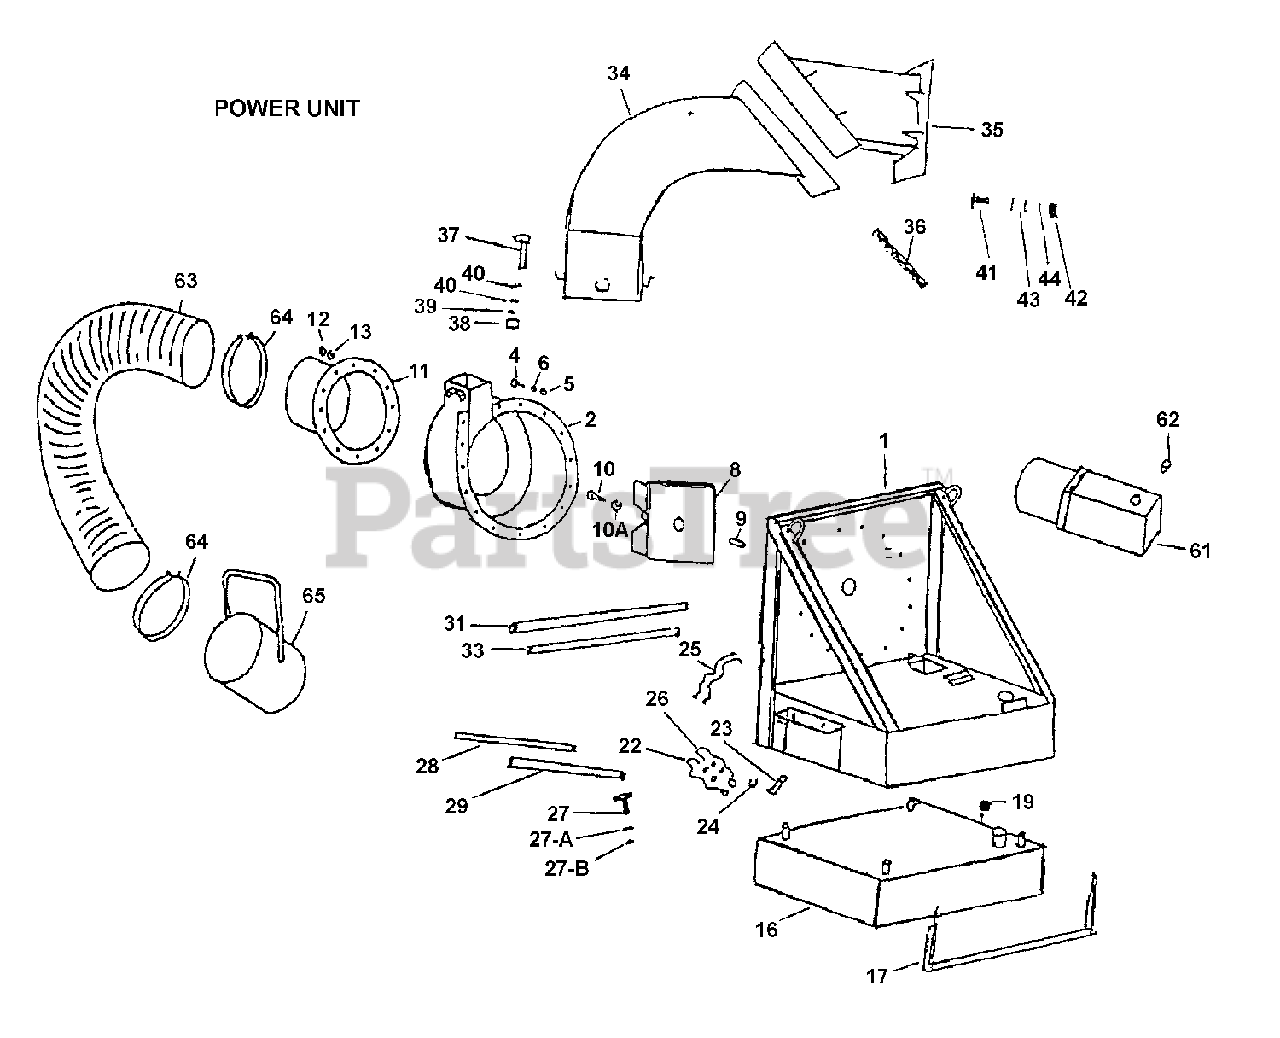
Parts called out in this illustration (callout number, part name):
1	Loader Base (29 HP)
1	Loader Base (35 HP)
2	Blower Housing (29 HP)
2	Blower Housing (w/Bolt-in Wear Liner) (35 HP)
4	3/8-16 x 1 Hex Bolt
5	3/8-16 Hex Nut
6	3/8 Lock Washer
8	Impeller (29 HP)
8	Impeller (35 HP)
9	Impeller Key (35 HP)
10	5/8 x 2 Impeller Bolt (35 HP)
10A	5/8 Lock Washer (35 HP)
11	16" Intake Flange (35 HP)
12	1/2 Hex Nut (35 HP)
13	1/2 Lock Washer (35 HP)
16	Fuel Tank (29 HP)
16	Fuel Tank (2009 EPA) (35 HP)
17	Fuel Tank Strap (29 HP)
19	Fuel Cap - Specify Gas (29 HP)
19	Fuel Cap (2009 EPA) (35 HP)
22	Valve Assembly
23	Valve Handle
24	Valve Handle Holder
26	Replacement Micro Switch for Valve Assembly
27	1/4-20 x 1-1/4 Hex Bolt (Valve Assembly Mount)
27A	1/4 Lock Washer
27B	1/2-20 Hex Nut
28	Hydraulic Hose 1/2 x 23 Valve to Jack
29	Hydraulic Hose 1/2 x 43 Valve to Jack
31	Hydraulic Hose 1/2 x 63 Valve to Hydraulic Power Unit
33	Hydraulic Hose 1/2 x 49 Valve to Hydraulic Power Unit
34	Stack & Elbow Assembly (w/Wear Liner) (29 HP)
34	Stack & Elbow Assembly (w/Wear Liner) (35 HP)
35	Discharge Stack - Leaf Box Side (29 HP)
35	Discharge Stack - Leaf Box Side (35 HP)
36	Discharge Stack Gasket Set
37	1/2 x 4-1/2 Hex Bolt (29 HP)
37	1/2 x 1-3/4 Hex Bolt (35 HP)
38	1/2 Hex Nut
39	1/2 Lock Washer
40	1/2 Flat Washer
41	3/8-16 x 1-1/4 Hex Bolt
42	3/8-16 Hex Nut
43	3/8 Flat Washer
44	3/8 Lock Washer
61	Hydraulic Power Unit
62	Breather Cap
63	Intake Hose 12" x 10' (29 HP)
63	Intake Hose 16" x 7' Blue (35 HP)
64	12" Hose Clamp (29 HP)
64	16" Hose Clamp (35 HP)
65	12" Intake Nozzle (29 HP)
65	16" Intake Nozzle (35 HP)
